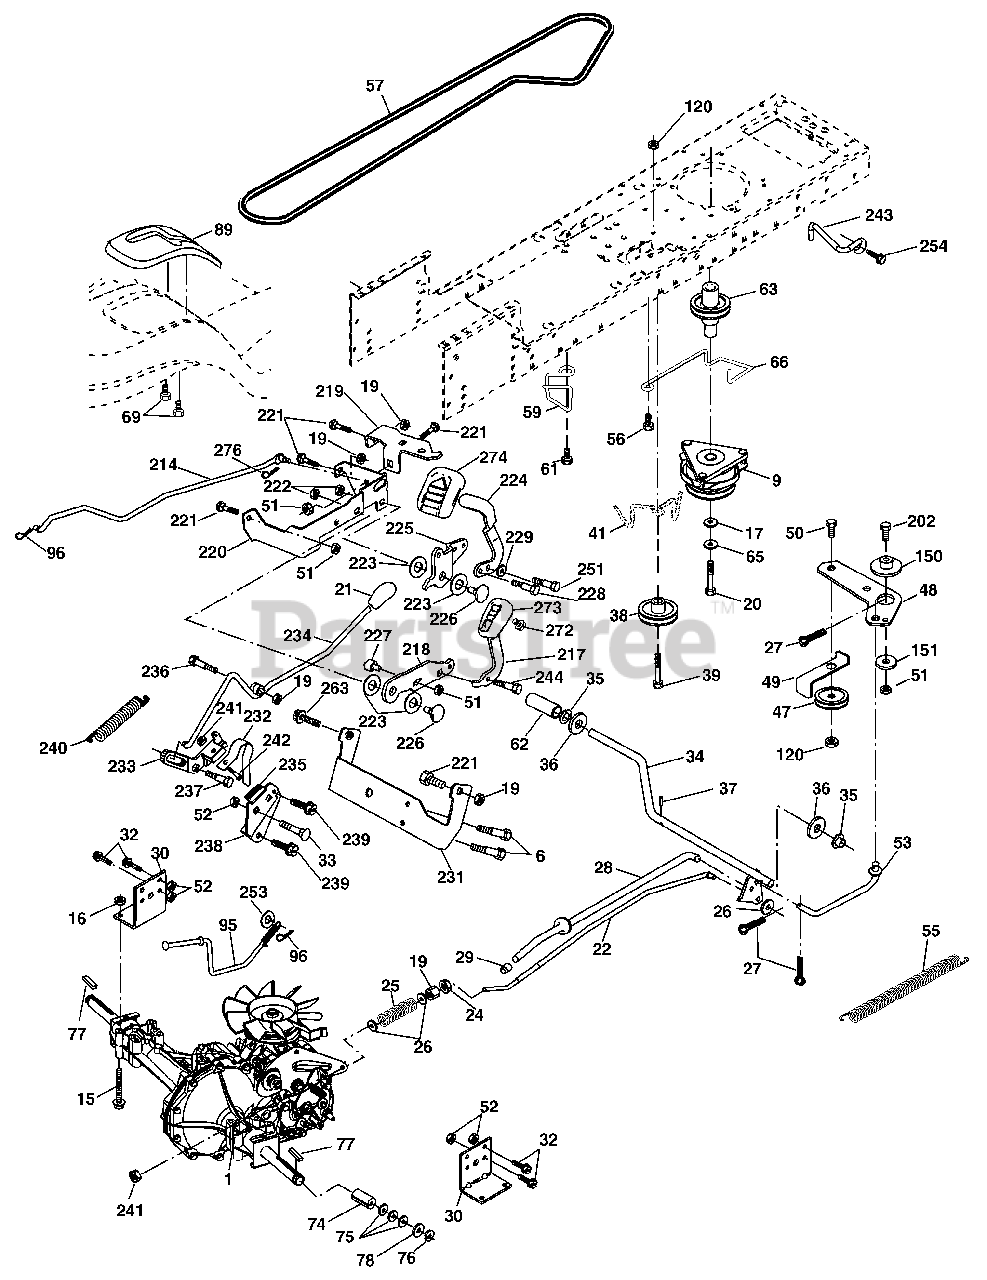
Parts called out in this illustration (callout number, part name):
6	Screw 5/16-18 x 3/4
9	Clutch Elec
15	Bolt Hex Flghd 5/16-18 Gr. 5
16	Nut Lock Hex W/Ins. 5/16-18 unc
17	Washer 1-1/2 OD x 15/32 ID x .250
19	Nut Lock Hex W/Wsh 3/8-16 unc
20	Bolt Hex 7/16-20 x 4 x Gr. 5-1.5
21	Knob Custom Control Cruise
22	Rod, Brake
24	Nut, Hex Jam 3/8-16 unc
25	Spring, Brake Rod
26	Washer
27	Pin Cotter 1/8 x 3/4 CAD.
28	Rod, Parking Brake
29	Cap, Brake, Park
30	Bracket, Transaxle
32	Bolt Hex Hd 5/16-18 unc x 3/4
33	Bolt Rdhd Sqnk 5/16-18 unc x 3/4
34	Shaft, Foot Pedal
35	Bearing, Nylon
36	Washer
37	Pin, Roll
38	Pulley, Composite, Flat
39	Bolt Rdhd 3/8-16 x 2- 3/4 Gr. 5
41	Keeper, Belt Idler Flat
47	Pulley, Idler, V-Groove
48	Bellcrank Clutch Grnd Drw Stl
49	Retainer, Belt
50	Bolt
51	Nut Crownlock 3/8-16 unc
52	Nut, Crownlock 5/16-18 unc
53	Link, Clutch
55	Spring, Return, Clutch
56	Screw 3/8-16 x 1-1/4
57	V-Belt, Ground Drive
59	Keeper, Center Span
61	Screw 3/8-16 x .875
62	Cover, Pedal
63	Pulley, Engine
65	Washer
66	Keeper Belt Engine
69	Screw
74	Spacer, Axle
75	Washer 25/32 x 1-1/4 x 16 Ga.
76	E-Ring
77	Key, Square
78	Washer 25/32 x 1-5/8 x 16 Ga.
89	Console, Shift
95	Rod Bypass
96	Retainer Spring 1" Zinc/Cad
120	Nut Lock Flg 3/8-16 unc
150	Spacer Retainer
151	Washer 13/32 x 2 x 10 Ga.
202	Bolt Carr Sh 3/8-16 x 1-3/4 Gr. 5
214	Link Transaxle
217	Pedal Assy, Reverse, with Pad
218	Arm Control Pedal Reverse
219	Bracket Frest Pdl Ctrl. Hyd
220	Bracket Mtg. Pedal Control
221	Bolt Rdhd Sqnk 3/8-16 unc x 3/4
222	Nut Crownlock 7/16-14 unc
223	Washer Nylon 11/16 ID x .060
224	Pedal Forward
225	Arm Control Pedal Forward
226	Bolt Pivot Spacer
227	Cam Reverse Pedal LT
228	Bolt Shoulder 5/16-18
229	Washer Serrated 5/16 x .75
231	Strap Torque
232	Actuator Cruise Disengage
233	Pawl Control Cruise
234	Lever Control Cruise
235	Sector Control Cruise
236	Bolt Shoulder 3/8-16 unc 1/44
237	Bolt Shoulder 5/16-18
238	Arm Mtg. Cruise Sector
239	Screw Thdrol 5/16 x 1/2
240	Spring Return Cruise Control
241	Nut Centerlock 1/4-20 unc
242	Bolt Fin Hex 1/4-20 unc x .75
243	Bracket Anti-Rotation
244	Screw 5/16-18 x 5/8
251	Screw 5/16-18 x 1
253	Washer .3125 x .615 x 16 Ga.
254	Screw 3/8-16 x 1
263	Screw 3/8-16 x 3/4
272	Screw, 5/16-18 x 1/2 TT
273	Pad, Reverse Pedal
274	Cover Pedal Forward
